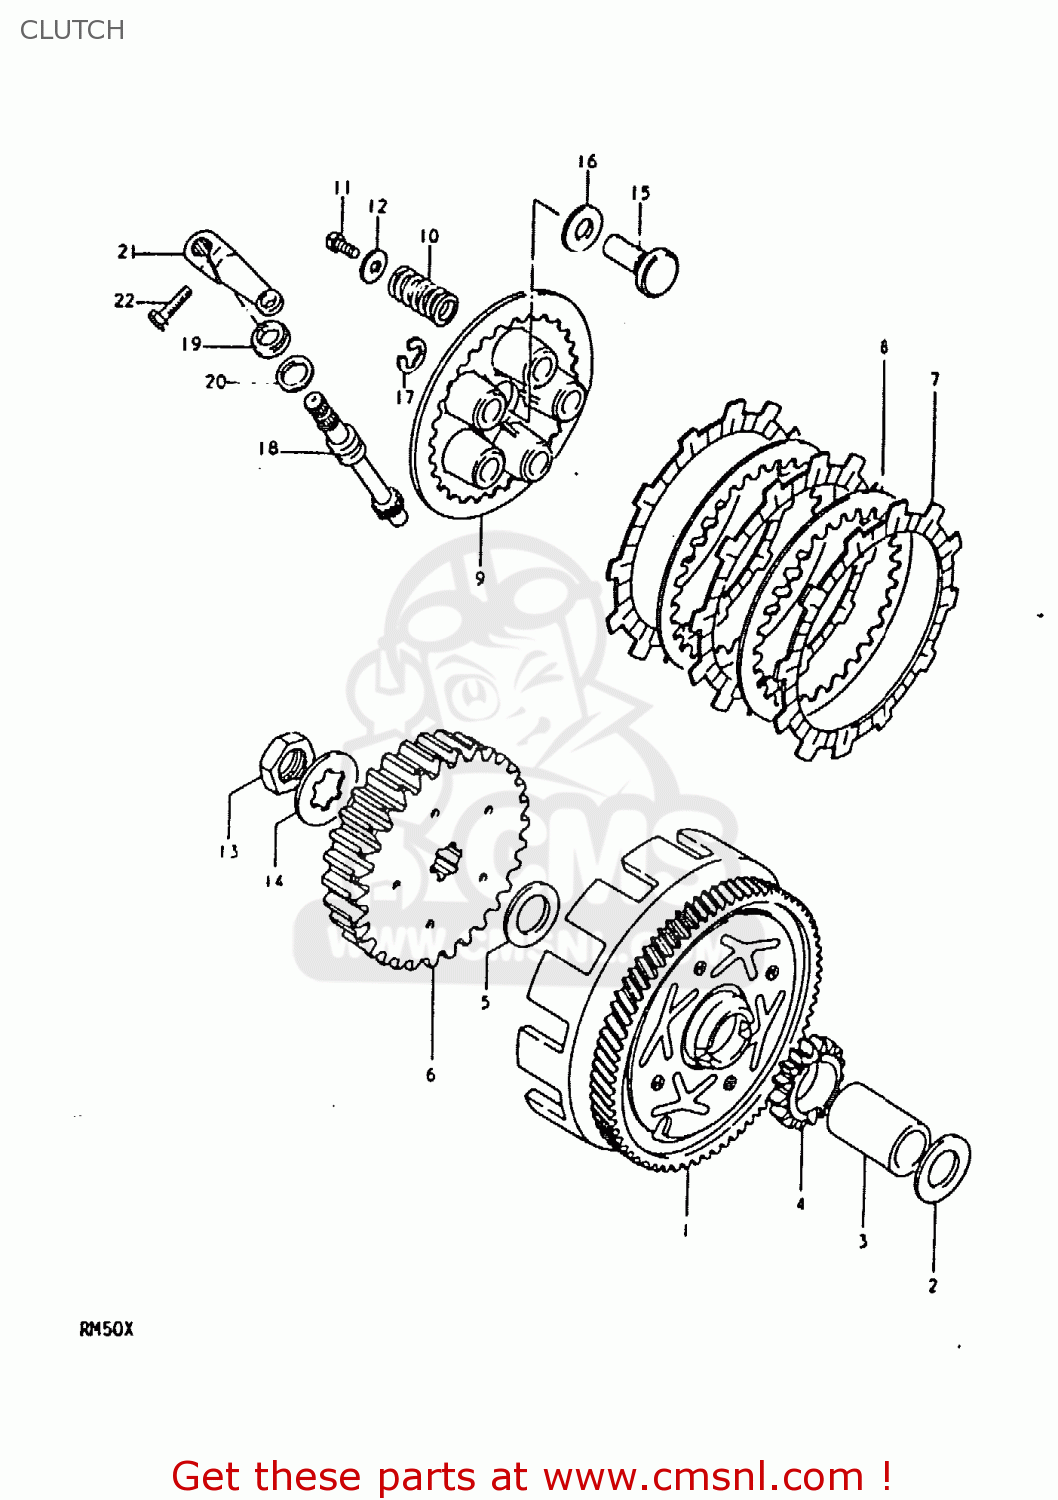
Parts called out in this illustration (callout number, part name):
1	GEAR ASSEMBLY,PRIMARY DRIVE
2	WASHER,THRUST
3	SPACER
4	GEAR,KICK STARTER DRIVE
5	WASHER
6	HUB,CLUTCH SLEEVE
7	PLATE,CLUTCH DRIVE
8	PLATE,CLUTCH DRIVEN (NAS)
9	DISC,CLUTCH PRESSURE
10	SPRING
11	BOLT(5X16)
12	WASHER (5.5X16X1.2)
13	NUT
14	WASHER,LOCK
15	RACK,CLUTCH RELEASE
16	BEARING(10X22X2.8)
17	E RING 8MM
18	PINION,CLUTCH RELEASE
19	OIL SEAL
20	WASHER (12X17X1)
21	ARM,CLUTCH RELEASE
22	BOLT, UPPER
